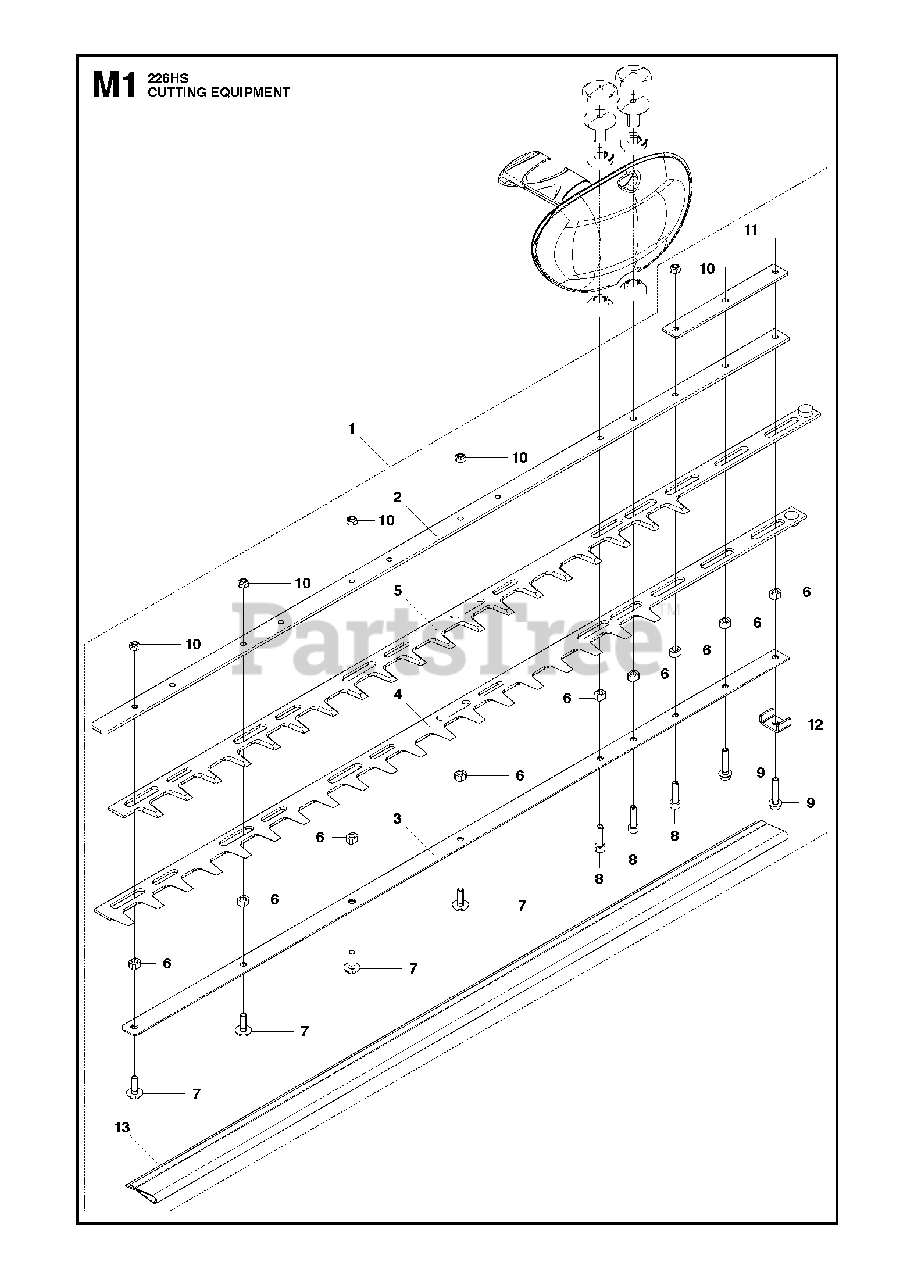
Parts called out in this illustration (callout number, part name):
1	BLADE ASSY
2	PLATE UPPER
3	PLATE LOWER
4	BLADE LOWER
5	BLADE UPPER
6	SPACER
7	SCREW
8	BOLT
9	BOLT
10	NUT
11	PLATE
12	BRACKET
13	COVER
